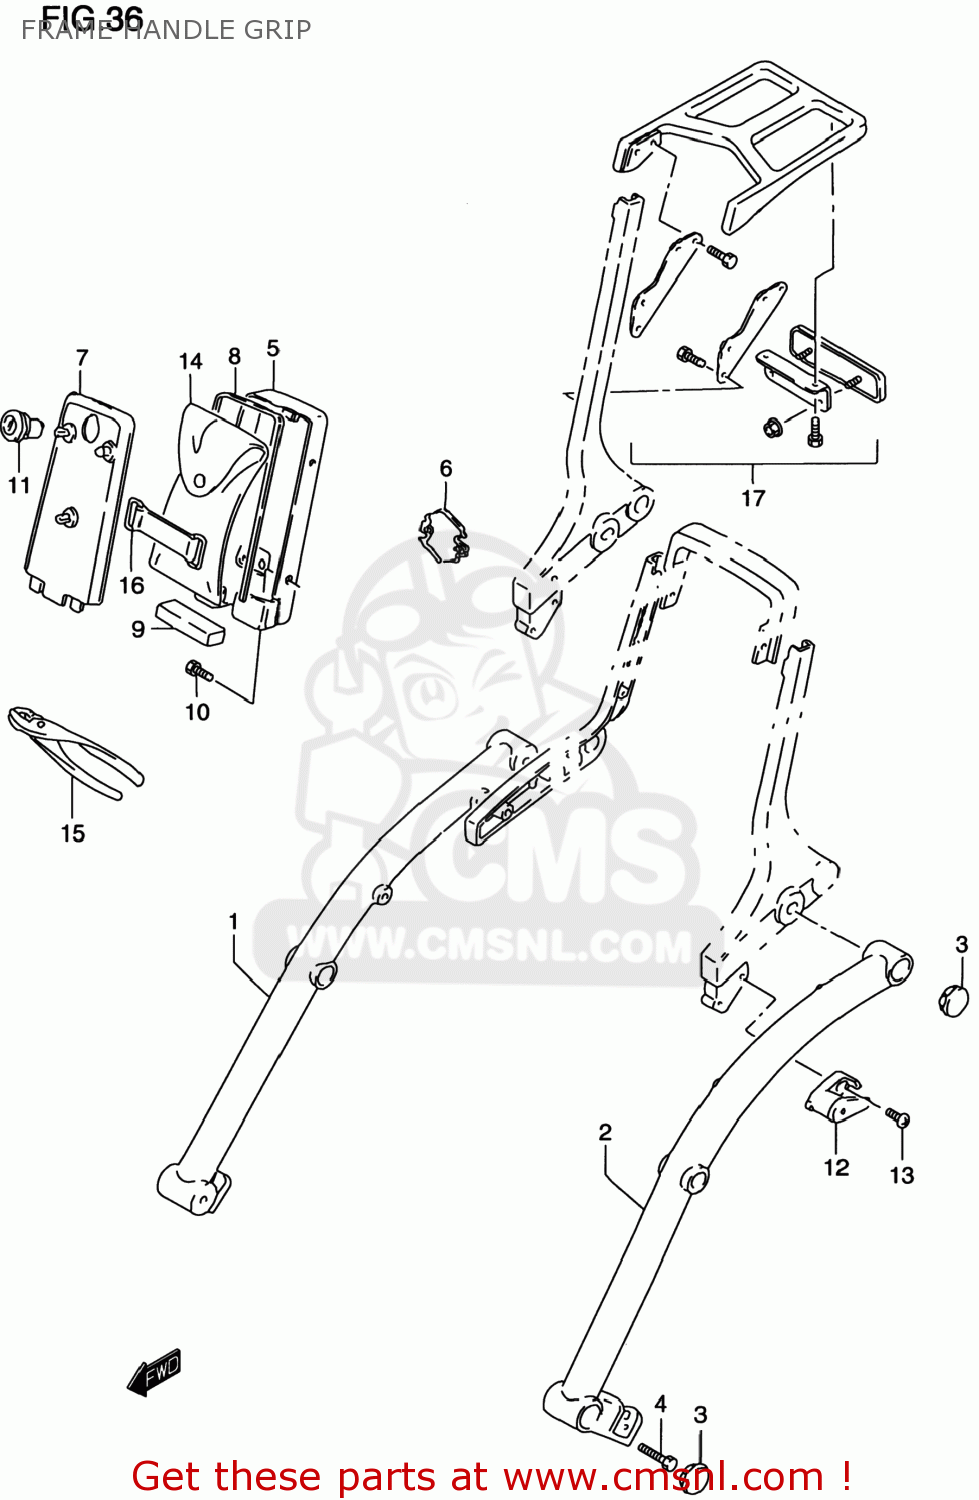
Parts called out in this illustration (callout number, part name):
1	GRIP,FRAME HANDLE,RIGHT
2	GRIP,FRAME HANDLE,LEFT
3	CAP,FRAME HANDLE GRIP
4	BOLT
5	HOLDER,TOOL,REAR
6	EMBLEM,TOOL HOLDER RR
7	HOLDER,TOOL FR
8	MOLDING,TOOL HOLDER RR
9	CUSHION,TOOL BACK
10	BOLT
11	LOCK SET,TOOL HOLDER
12	LOCK SET,HELMET
13	SCREW
14	TOOL ASSY
15	PLIER(150)
16	BAND
17	CARRIER SET,SPORT
